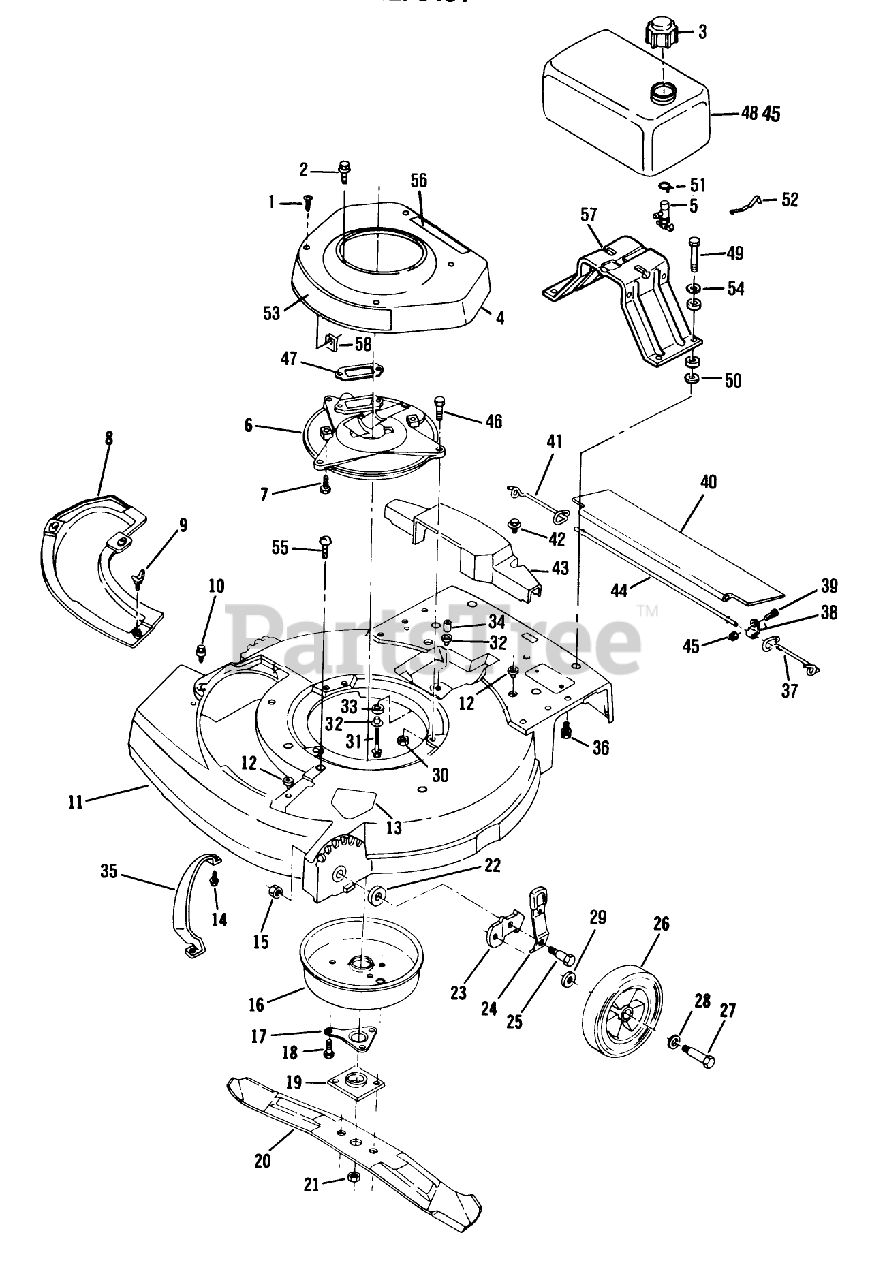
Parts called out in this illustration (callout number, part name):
1	SCREW - SELF TAPPING
2	SCREW SEMS SM
3	Fuel Cap
5	VALVE&SCREEN SM
6	PLATE F
7	SCREW V
9	WING SCREW LAWRE
15	LOCKNUT
16	MUFFLER COVER F
17	SUPPORT F
18	SCREW
19	PLATE AND COLLAR ASM
21	NUT-BLADE
22	WASHER
24	Knob and Spring Assembly
25	BOLT
26	WHEEL & TIRE
27	BOLT-SHOULDER
28	SPACER
29	WASHER WROUGHT
30	NUT-LOCK F
32	SPACER ECK PRES
33	GROMMET
34	SPACER
35	BAR-TOE
36	SCREW
37	SPRIG T/SHLD ASOC
38	CLAMP ROD KMC
40	SHIELD
41	SPRING;TRAILING SHIELD RH
42	SCREW SEMS TRM HEX HD
43	COVER
44	ROD 21" ADVANCE
45	LOCKNUT E
46	SCREW-HH
48	TANK - FUEL
49	BOLT PIONEER
51	CLAMP - HOSE S
52	SPRING
54	WASHER
57	BRACKET
58	PUSHNUT F
